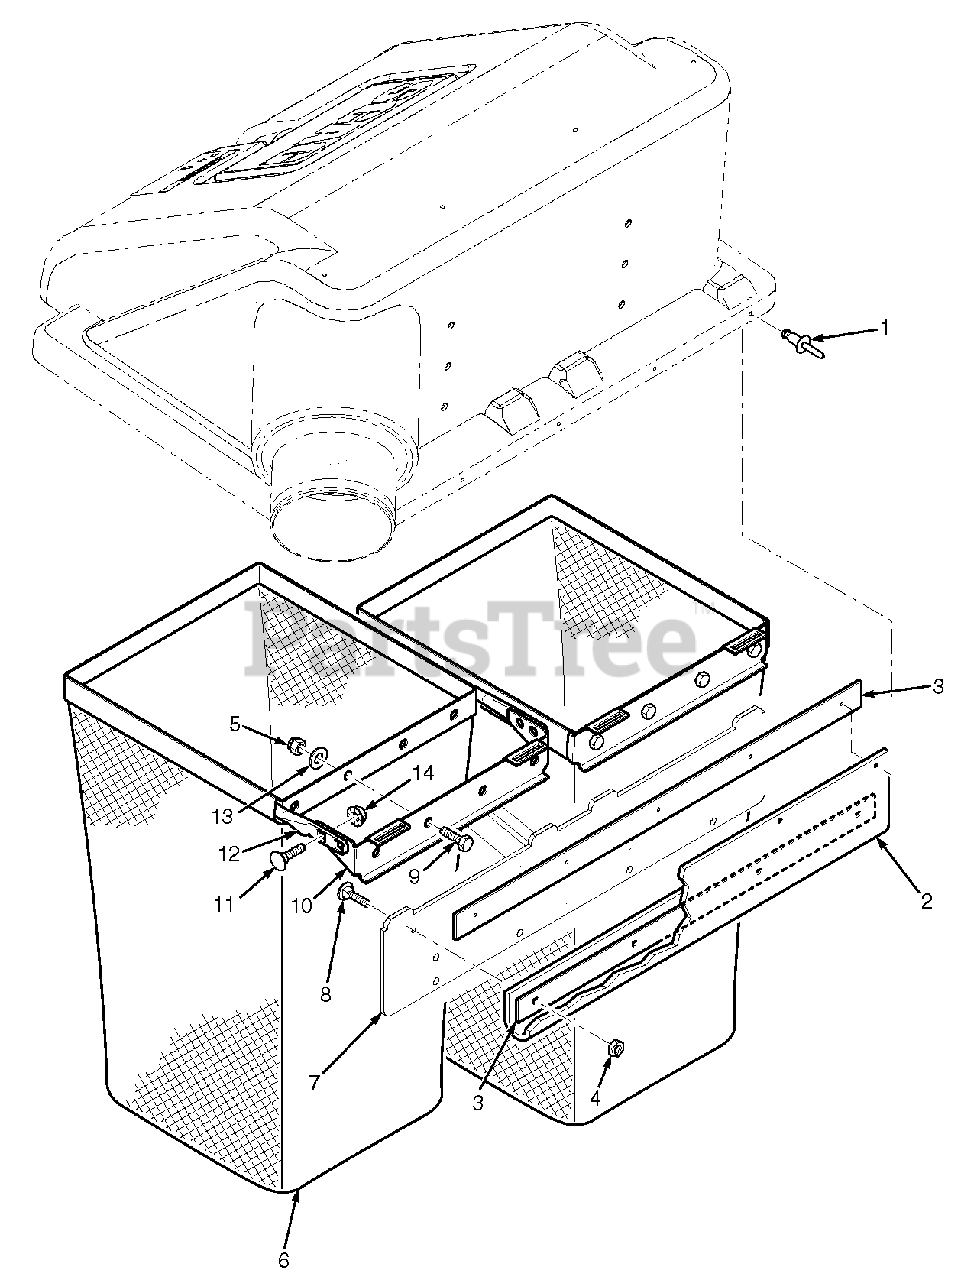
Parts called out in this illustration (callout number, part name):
1	Pop Rivet, 3/16 x .652
2	Seal, GC Hood
3	Retainer, Seal
4	Nut, Center Lock 1/4-20
5	Nut, Elastic Stop 5/16-18
6	Bag Assembly
7	Frame Weldment, Bag Support
8	Bolt, Hex Head 1/4-20 x 3/4"
9	Bolt, Hex Head 5/16-18 x 3/4"
10	Mount, Bag Frame Tube
11	Bolt, Carriage 5/16-18 x 3/4"
12	Tube, Bag Support
13	Flatwasher, 5/16-.375 x .875 x .083
14	Nut, Serrated Flange 5/16-18
